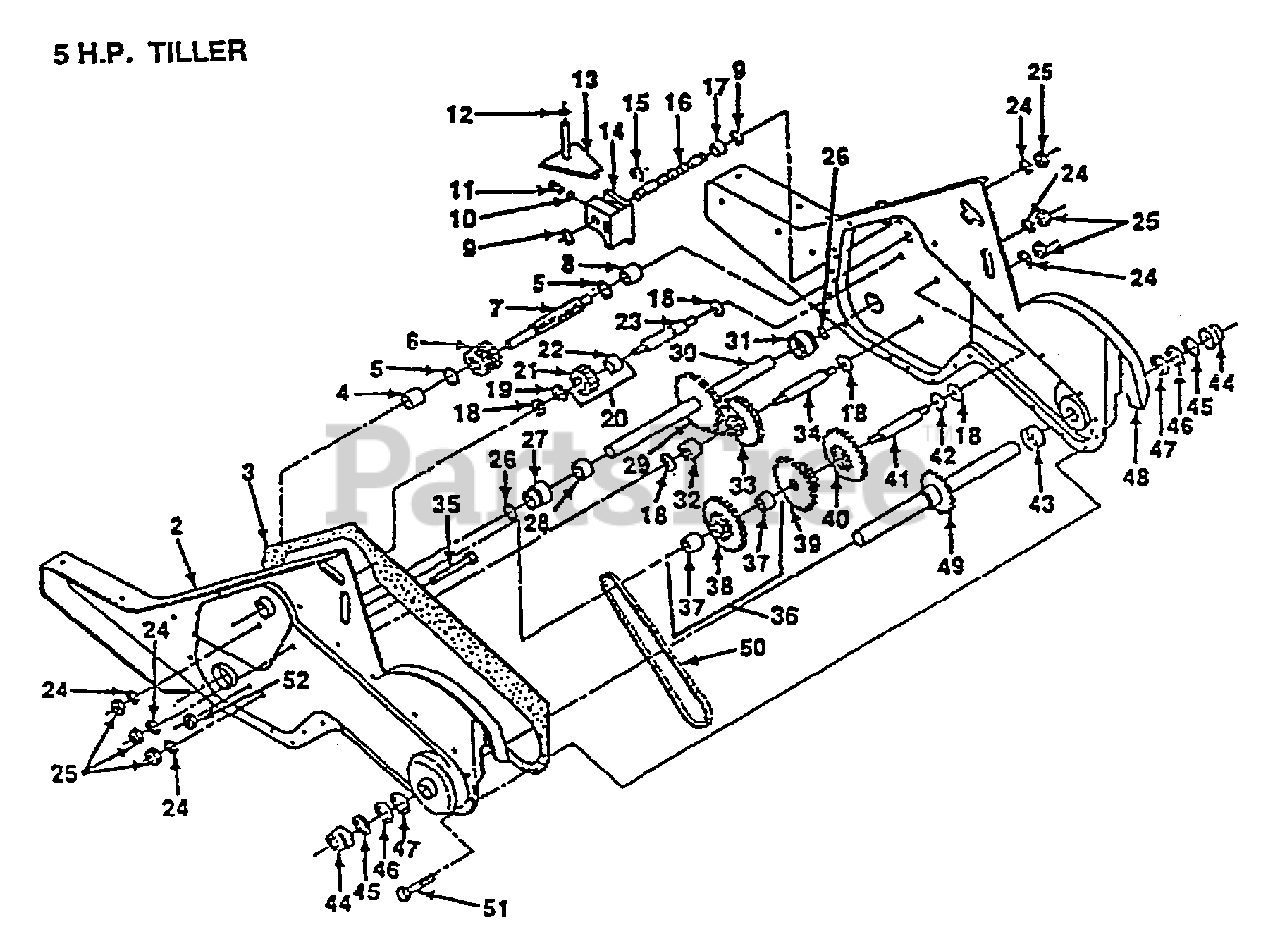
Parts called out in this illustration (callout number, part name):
3	GASKET TI
4	NEEDLE BRNG LT
5	"T, BEARING"
6	PINION-INPUT CRT
7	SHAFT-INPUT CRT
8	"TI, BEARING"
9	WASHER SEAL CRT
11	SPRING-SHIFT CRT
12	O-RING TI
13	ARM ASSY CRT
14	SHIFT FORK TI
15	KLIP RING
16	SHAFT SHIFT CRT
17	SPACER SPLIT CRT
18	WASHER
19	KLIP RING
20	GEAR ASSY CRT
21	GEAR-REV IDLR CRT
22	NEEDLE BEARING TI
23	SHAFT CRT
24	LOCKWASHER
26	O RING CRT
27	"CRT, BEARING"
28	BUSHING TI
29	CHAIN CRT
32	SPACER TI
33	SPRCKT 8 GEAR CRT
34	SHFT 2ND RED. CRT
35	SCRW WHIZ LOK CRT
37	BEARING
39	GEAR TI
40	GEAR TI
41	REDUCTION SHFT TI
42	BRNG RACE
43	SPACER TI
44	CUP.FORMED.
45	RING SPIRAL CRT
49	SHAFT ASSY TI
50	CHAIN.50 LINK TI
51	SCREW CRT
52	NUT.HEX.5/16-18
53	GREASE PREMIUM-1
